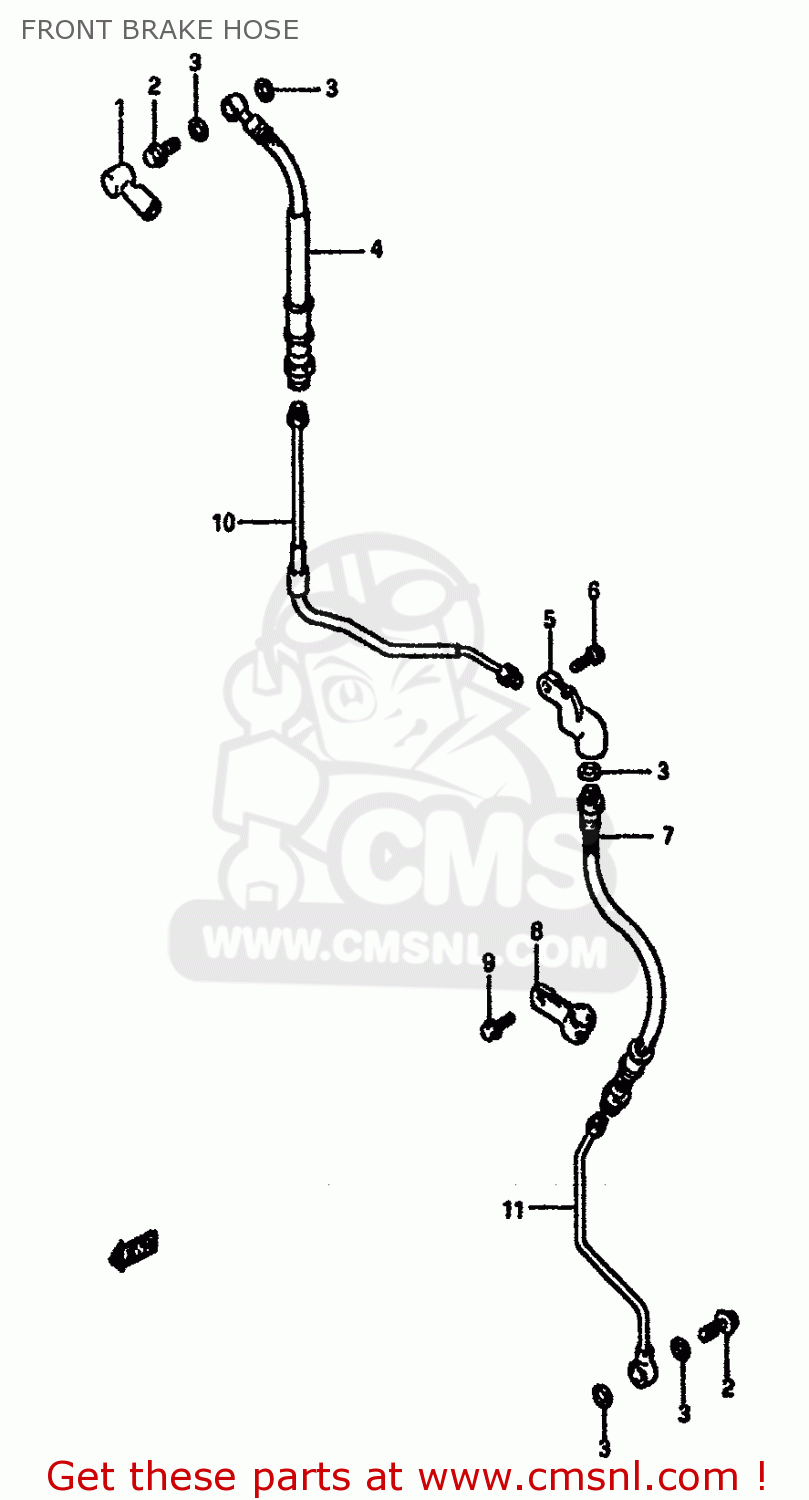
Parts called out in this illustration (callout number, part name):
1	BOOT,MASTER CYLINDER
2	BOLT,UNION
3	WASHER(10X15X1.5)
4	HOSE,FRONT BRAKE NO.1
5	JOINT,FRONT BRAKE
6	BOLT
7	HOSE,FR BRAKE NO.2
8	CLAMP,FRONT BRAKE HOSE
9	BOLT
10	PIPE,FRONT BRAKE NO.1
11	PIPE,FRONT BRAKE NO.2
